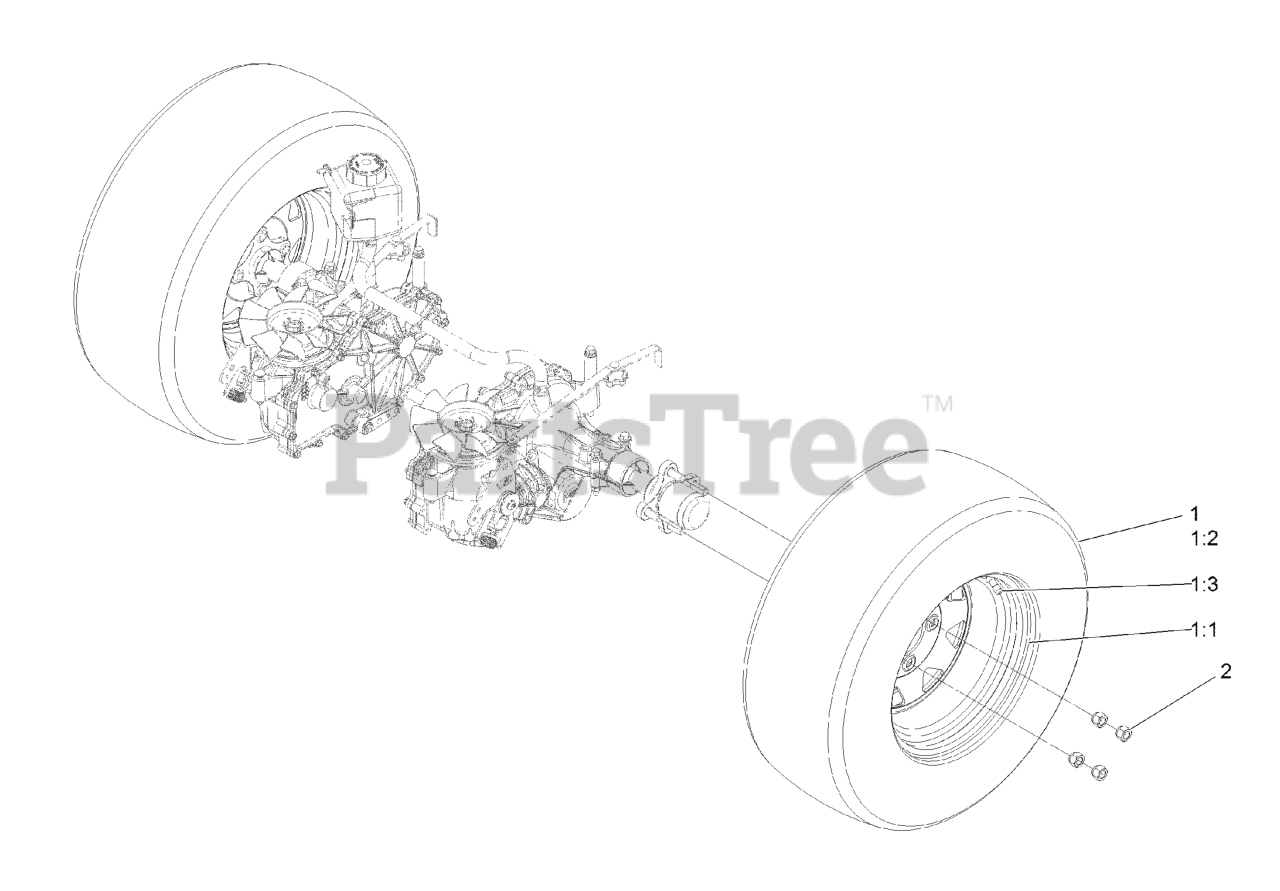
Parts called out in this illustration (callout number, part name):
1	WHEEL AND TIRE ASM
1:3	Stem-Valve
2	NUT-LUG
